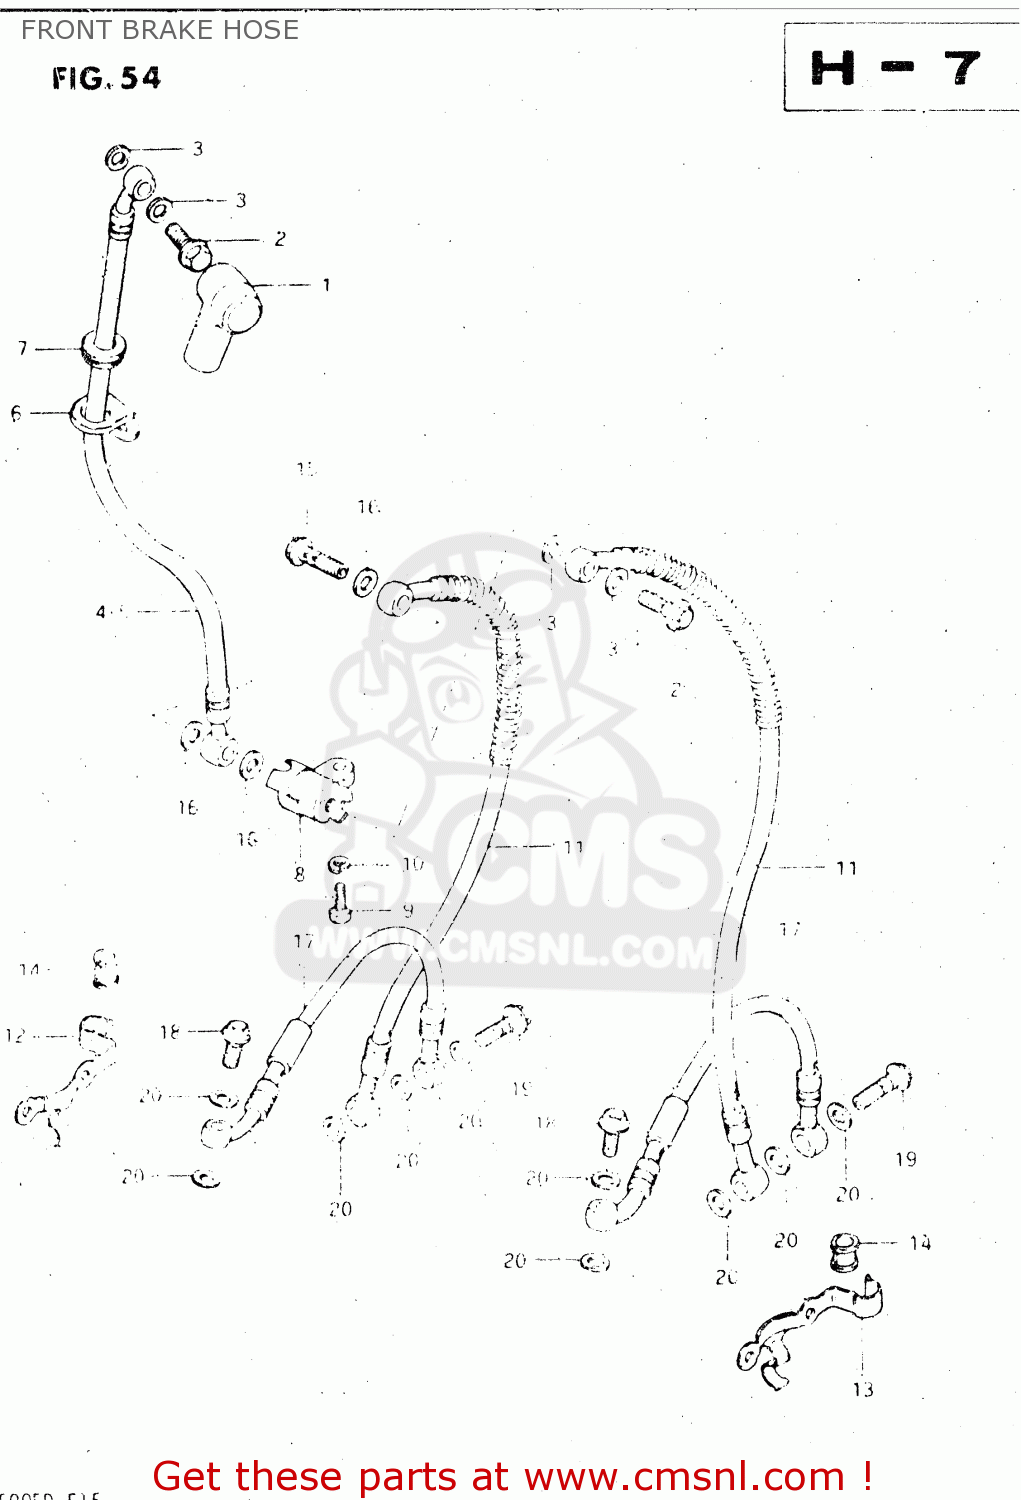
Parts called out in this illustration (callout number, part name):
1	BOOT,MASTER CYLINDER
2	BOLT,UNION
3	WASHER
4	HOSE,FRONT BRAKE
5	HOSE, BRAKE NO.1 (FLAT HANDLEBAR)
6	GUIDE,BRAKE HOSE NO.1
7	GROMMET
8	JOINT,BRAKE HOSE
9	BOLT
10	LOCK WASHER
11	HOSE, BRAKE NO.2
12	CLAMP RH
13	CLAMP LH
14	BUSH,BRAKE HOSE GUIDE,NO.2
15	BOLT,UNION
16	WASHER
17	HOSE,ANTI-NOSE DIVE
18	BOLT UNION
19	BOLT,UNION
20	WASHER
